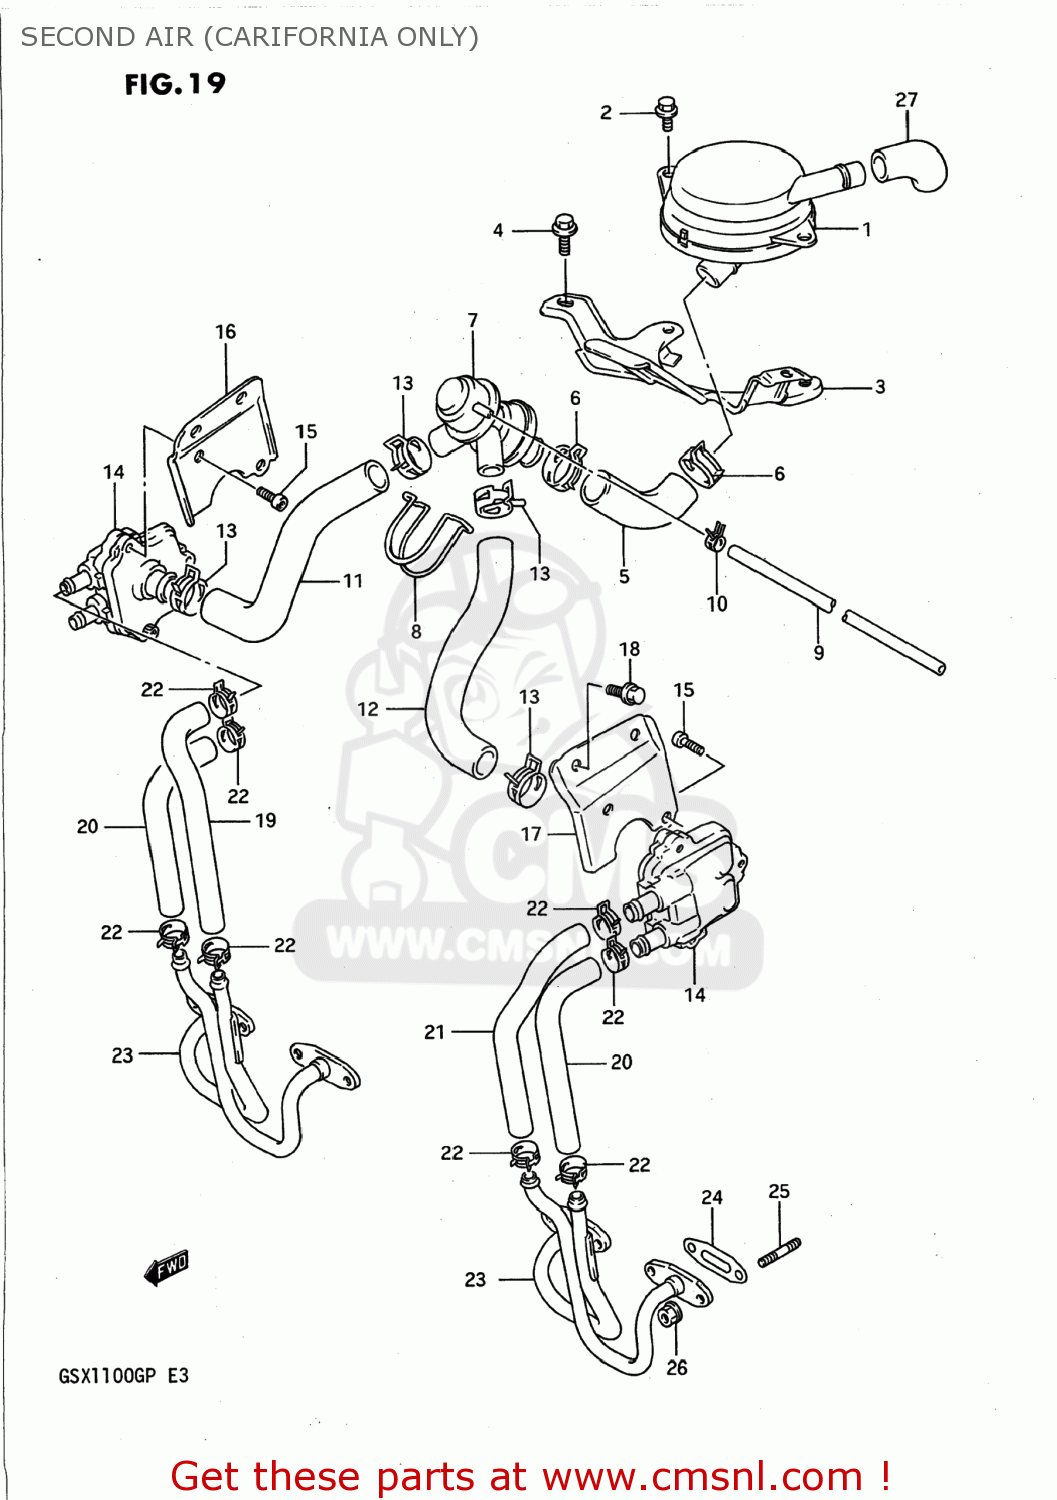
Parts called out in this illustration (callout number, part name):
1	CLEANER ASSEMBLY,SECOND AIR
2	BOLT
3	BRACKET COMP,SECOND AIR C
4	BOLT
5	HOSE,SECOND AIR NO.3
6	CLIP
7	VALVE ASSY,2ND AIR SWITCHING
8	CLAMP,SWITCHING VALVE
9	HOSE
10	CLAMP
11	HOSE,SECOND AIR NO.2,RIGHT
12	HOSE,SECOND AIR NO.2,LEFT
13	CLIP
14	VALVE ASSY,2ND AIR REED
15	BOLT
16	BRACKET,SECOND AIR REED VALVE
17	BRACKET,SECOND AIR REED VALVE
18	BOLT
19	HOSE,SECOND AIR NO.1,RIGHT,INLET
20	HOSE,SECOND AIR NO.1,OUTLET
21	HOSE,SECOND AIR NO.1,LEFT,INLET
22	CLIP
23	PIPE,2ND AIR,L
24	GASKET,SECOND AIR PIPE (NAS)
25	STUD BOLT
26	NUT 6MM
27	HOSE,SECOND AIR CLEANER
